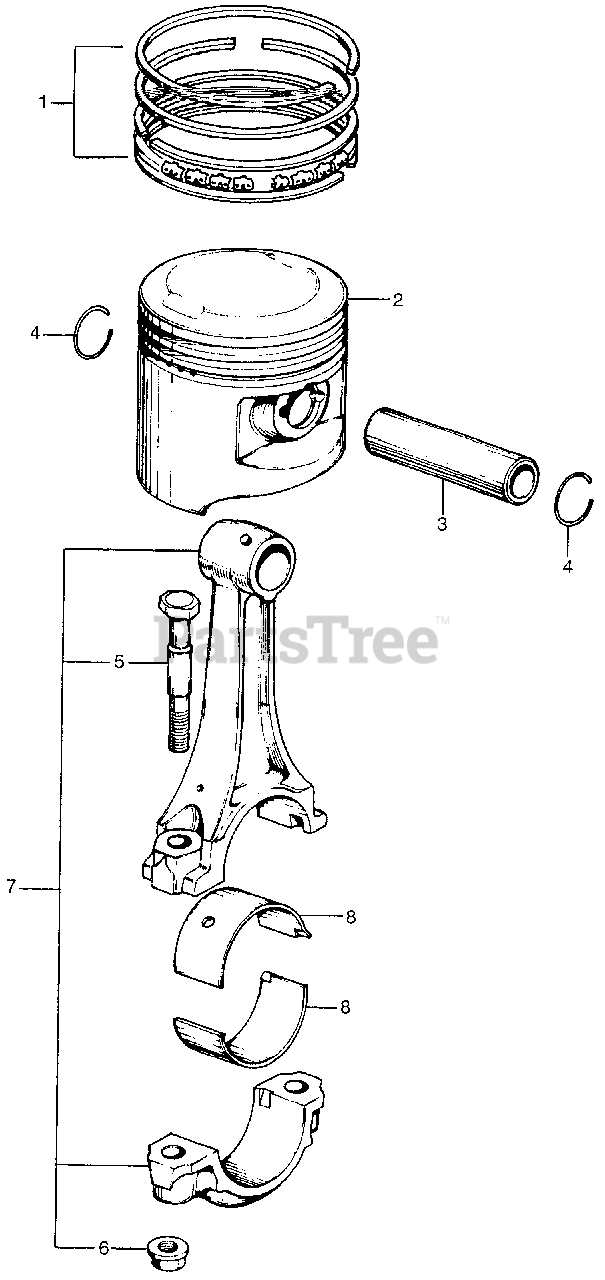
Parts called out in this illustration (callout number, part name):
1	RING SET, PISTON (STD)
1	RING SET, PISTON (OS 0.25) (OS)
1	RING SET, PISTON (OS 0.50) (OS)
2	PISTON (STD)
2	PISTON (OS 0.25) (OS)
2	PISTON (OS 0.50) (OS)
3	PIN, PISTON (STD)
3	PIN, PISTON (0.1) (OS)
3	PIN, PISTON (0.2) (OS)
3	PIN, PISTON (0.3) (OS)
4	CLIP, PISTON PIN
4	CLIP, PISTON PIN (17MM)
5	BOLT, CONNECTING ROD
6	NUT, CONNECTING ROD
7	ROD ASSY. (NOT AVAILABLE)
8	BEARING, CONNECTING ROD
8	BEARING, CONNECTING ROD (NOT AVAILABLE)
